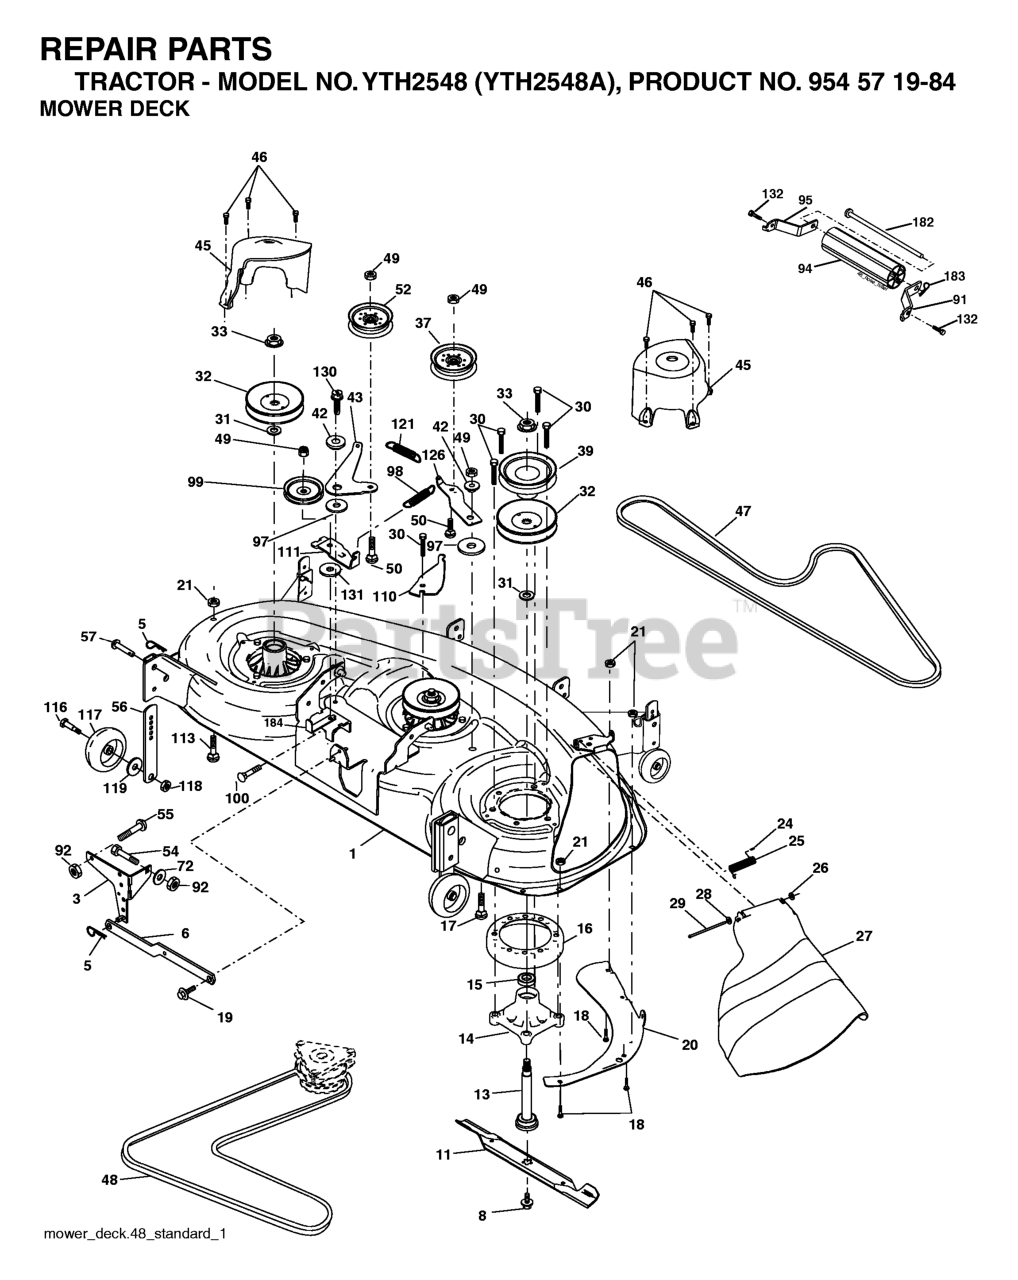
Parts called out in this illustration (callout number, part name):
1	DECK WELDMENT MOWER, 48
3	BRKT ASM SWAY BAR
5	RETAINER-SPRNG RB
6	BAR SWAY DECK
8	BOLT 7/16 ASM BLADE
11	48" HI-LIFT BLADE
13	SHAFT, ASM. MANDEREL SEALED
14	HOUSING, MANDREL 48"
16	STRIPPER.MANDREL.ROUND.BLACK
17	BOLT
18	BOLT
19	BOLT SHD 5/16-18
20	BAFFLE, VORTEX MWR
21	LOCKNUT
24	CAP-SLEEVE LT
25	SPRING, TORSION
26	NUT PUSH M
27	DEFLECTOR SUBS TO 532 180655
28	Washer 11/32 x 5/8 x 16 Ga SD
29	ROD.HINGE
30	SCREW, WASHER HEAD
31	WASHER.SPACER.MANDREL
32	PULLEY, MANDREL
33	NUT, FLG TOPLOCK 9/16"
37	PULLEY.IDLER.FLAT
39	PULLEY.DRIVEN.DECK.48'
42	SPACER RETAINER
43	ARM, IDLER SECONDARY
45	COVER.MANDREL.DECK.48"
46	SCREW.1/4-20X5/8
47	V-BELT, 48"SECONDARY
48	V-BELT PRIMARY 48"
49	NUT LOCK FLG 3/8-16 UNC
50	BOLT.3/8-16X1.50
52	PULLEY.IDLER.FLAT.46.PR.DR.
54	BOLT
55	BOLT D
56	BAR.ADJUST.WHEEL.ANTI.SCALP.BL
57	RIVET.PIN.HEAD.YELLOW.
72	WASHER
91	BRKT.NOSEROLLER.RH.48"
92	NUT
94	NOSE ROLLER 48"
95	BRKT.NOSEROLLER.LH.48"
98	SPRING PRIMARY DRIVE
99	IDLER PULLEY
100	BOLT
110	ARM, SPRING SECONDARY
111	ARM SPRING FIXED TENSION
113	BOLT.CARR.SQNK.5/16-18UNC.X3/4
116	SHOULDER BOLT
117	WHEEL GAGE DONUT
118	LOCKNUT
119	WASHER.5/16.FLAT.STE.STD.
121	SPRING.DRIVE.SECONDARY.48".DEC
126	ARM, IDLER PRIMARY DECK
130	SCREW 3/8-16X1
131	Washer 13/32 x 1.00 x 6 Ga.
132	SCREW, 3/8-16X3/4
182	ROD.ROLLER.NOSE.NARROW.48"
183	SPRING RETAINER
184	KEEPER BELT IDLER PLATED
